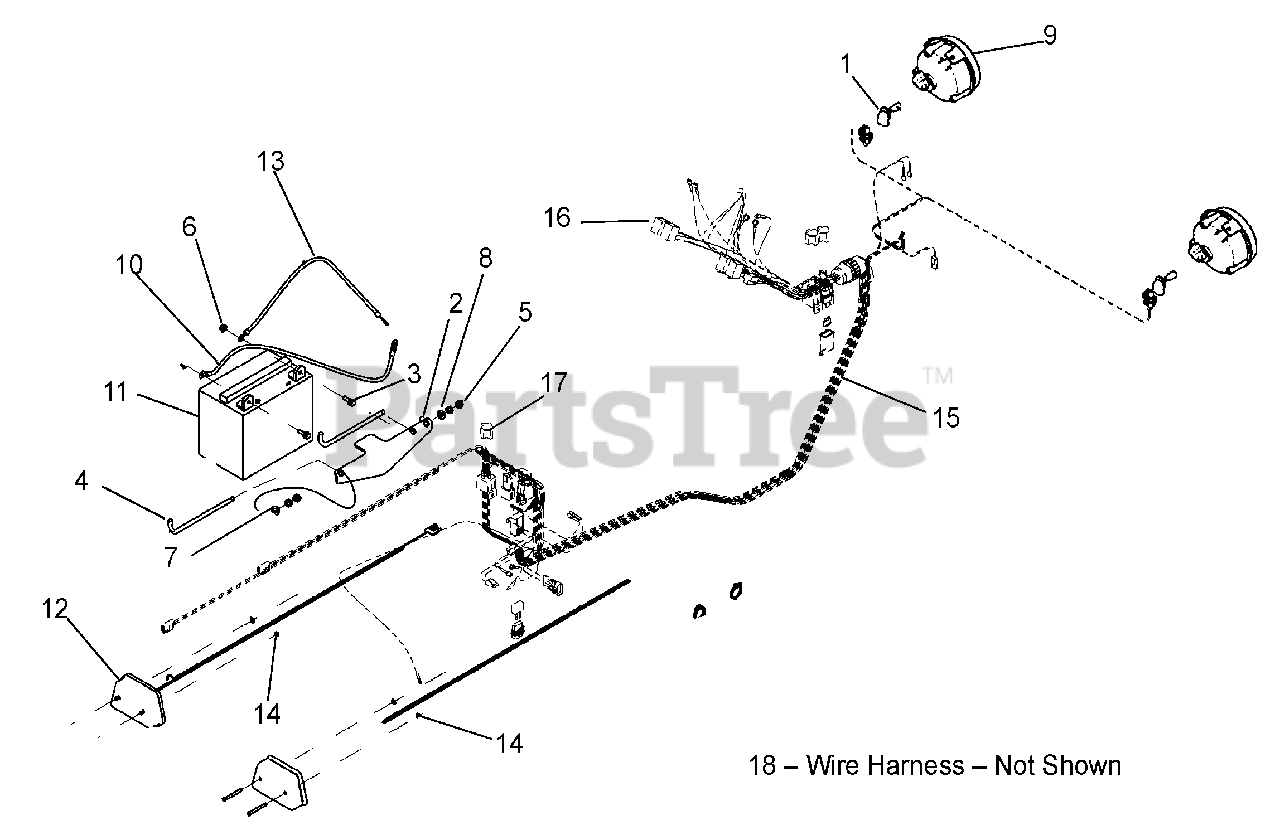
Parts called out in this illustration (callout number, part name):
1	HEADLIGHT BULB 37.5 WATT 894
2	HOLDOWN, BATTERY ST
3	SCREW, HEX FLANGE .25-20 X .625
4	SP HOOK 5/16-18 X 9 X 3 THREAD
5	NUT, HEX 5/16-18 YWZC
6	NUT, HEX FLANGE T-LOCK 1/4-20 YLW
7	WASHER, FLAT STEEL .312 X .734 X .065
8	WASHER, LOCK .31 X .078 REG YWZC
9	HEADLIGHT, ROUND
10	BATTERY CABLE POSITIVE 15 INCH
11	BATTERY (BUY LOCALLY BCI Group U1/U1R, Min. 300CA)
12	TAIL LIGHT, LED
13	20" 6GA NEGATIVE BLACK CABLE
14	PUSH RETAINERS 4 NON-THRD SHFT
15	WIRE HARNESS, MAIN
16	WIRE HARNESS, SUB DASH
17	RELAY, ISO MINI ELEC.
